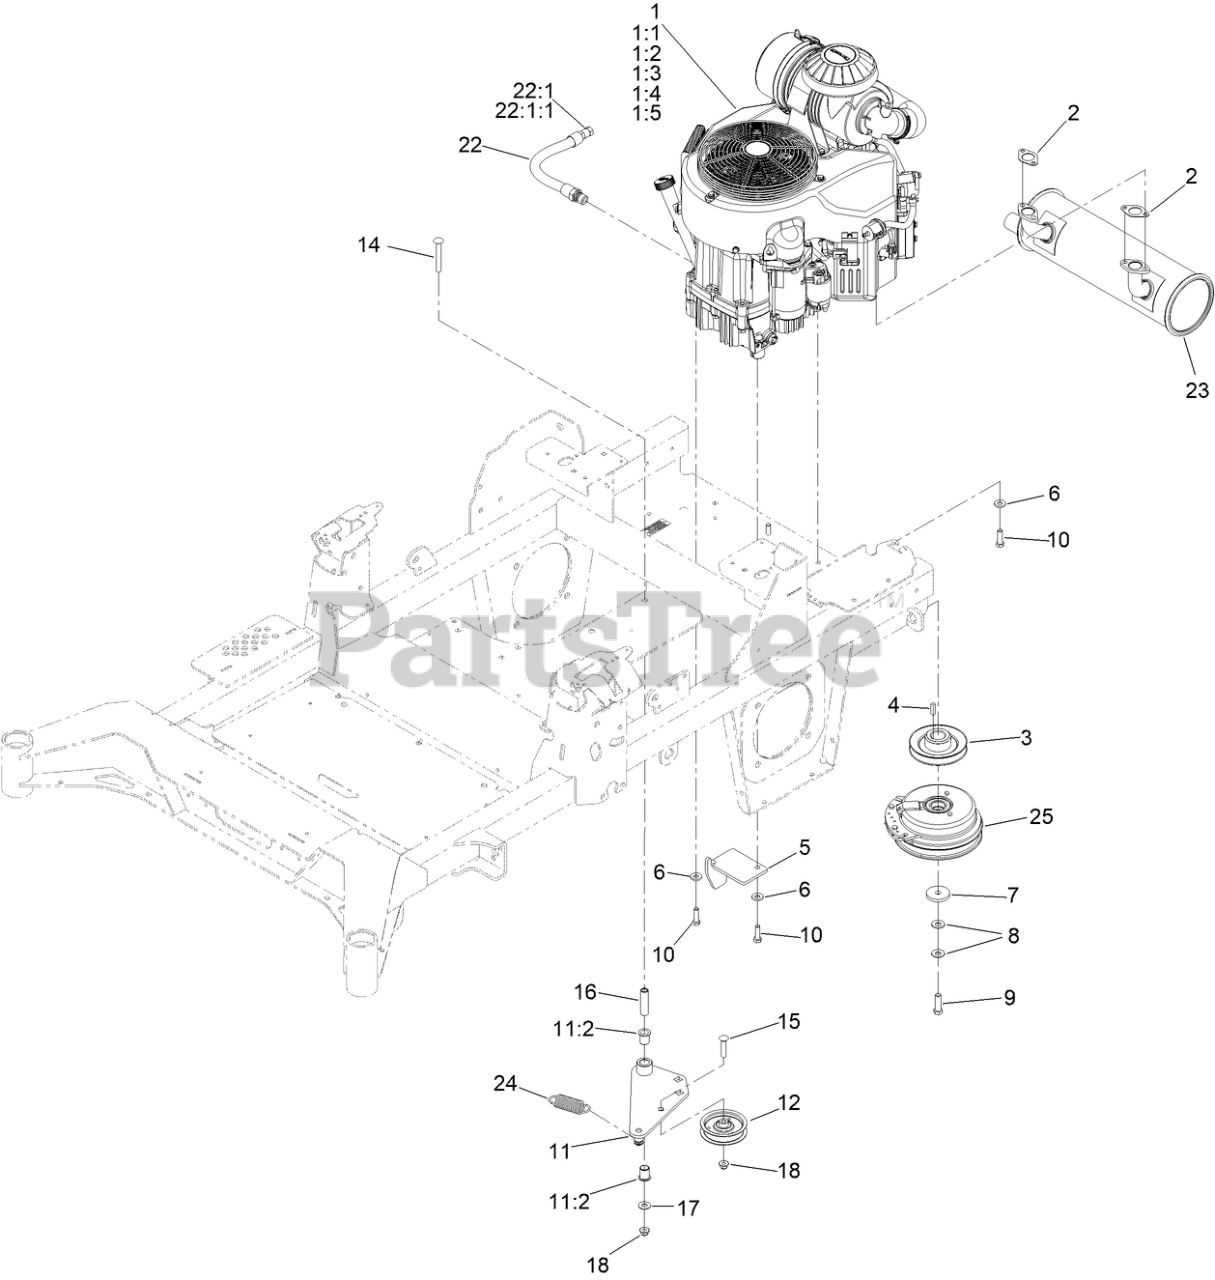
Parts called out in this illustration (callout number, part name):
1:1	FILTER-OIL
1:2	ELEMENT-FILTER, AIR (OUTER)
1:3	ELEMENT-FILTER, AIR (INNER)
1:4	FILTER-FUEL
1:5	SPARK PLUG
2	GASKET-EXHAUST
3	SHEAVE, W/HUB
5	ANCHOR-CLUTCH
6	WASHER-BELLEVILLE
7	WASHER-CLUTCH
8	WASHER-SPRING
9	SCREW-HH, W/LOCTITE
10	SCREW-HH
11	IDLER ARM ASM
11:2	BUSHING-FLANGE
12	PULLEY-IDLER, FLAT
14	SCREW-CARR
15	SCREW-CARR
16	BUSHING, IDLER PIVOT
17	WASHER-FLAT
18	NUT-HF, NI
22	ENGINE OIL DRAIN HOSE ASM
22:1	PLUG-HH
22:1:1	O-RING
23	MUFFLER
24	SPRING-IDLER
